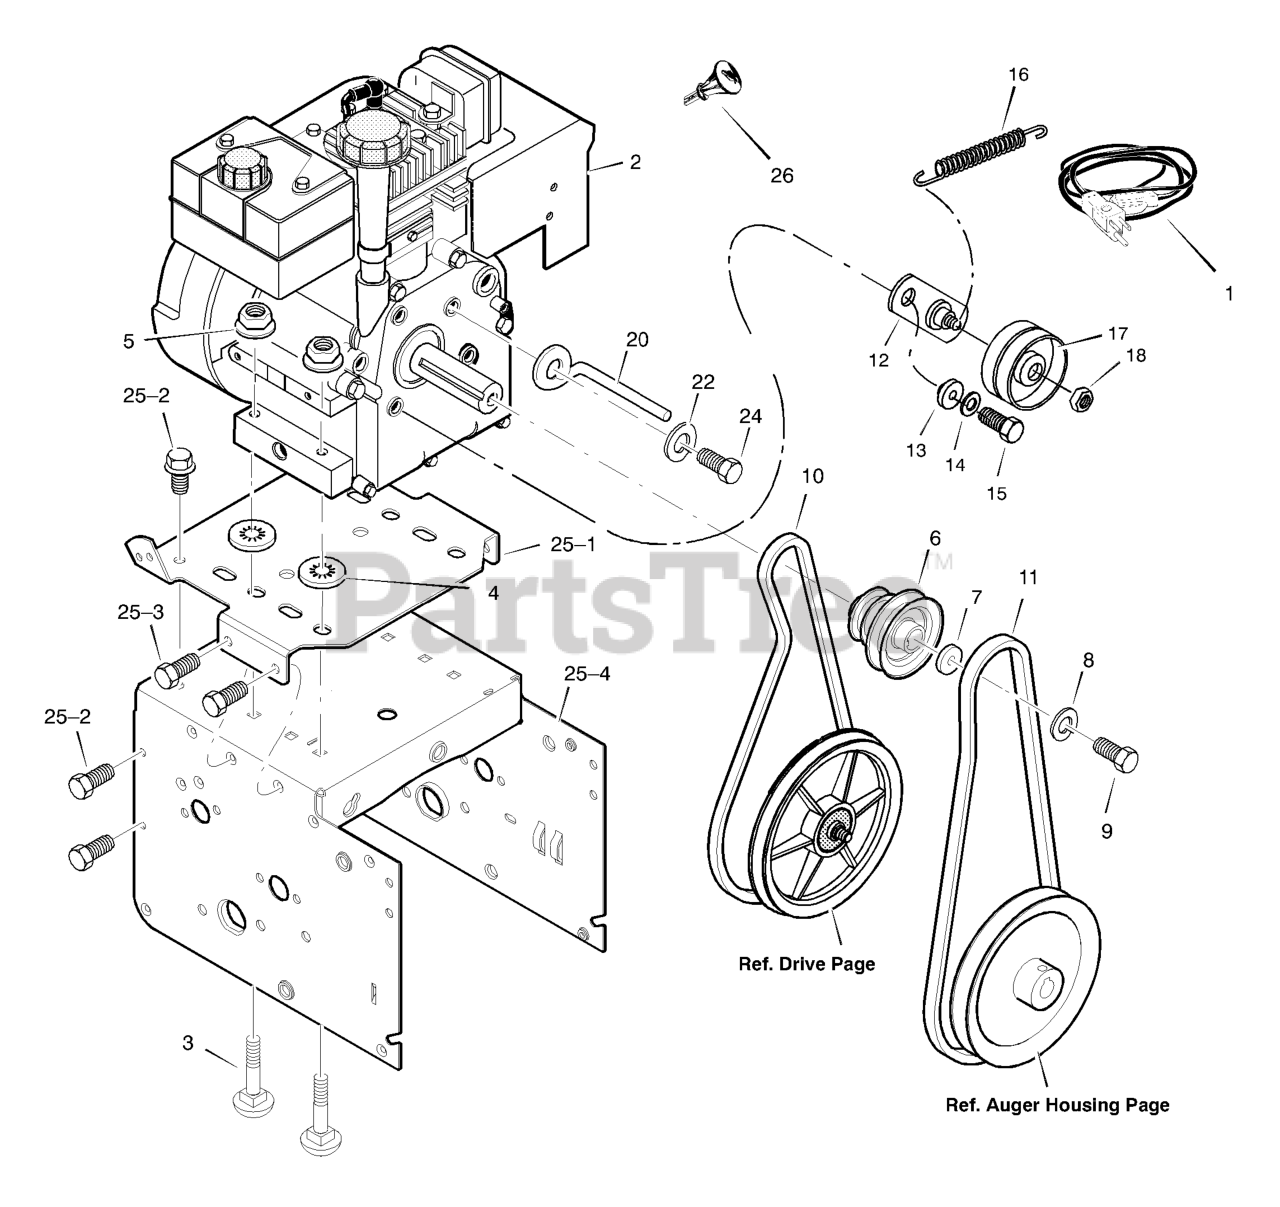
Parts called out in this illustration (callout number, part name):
1	CORD, STARTER 220V
2	ENGINE
3	BOLT, CARRIAGE 5/16-18
4	RETAINER, PUSH
5	NUT 5/16-18
6	PULLEY, ENGINE
7	WASHER
8	WASHER .38ID
9	SCREW, 3/8-24 x 1.00
10	BELT, V 3L
11	BELT, V 4L
12	BRACKET ASSEMBLY, IDLER
13	BUSHING, IDLER BRACKET
14	WASHER, SPLIT
15	SCREW 5/16-24 X 0.75
16	SPRING, IDLER TRACTION DRIVE
17	PULLEY, IDLER
18	NUT, JAM 3/8-16
20	GUIDE, BELT
22	WASHER .31X.58X.08
24	SCREW, 5/16-24 x 0.75
25-1	PLATE, ENGINE MOUNT
25-2	SCREW, TAP 1/4-20 X .63
25-3	SCREW, TAP 5/16-18 X .50
25-4	FRAME, MOTOR BOX
26	KEY, ENGINE
